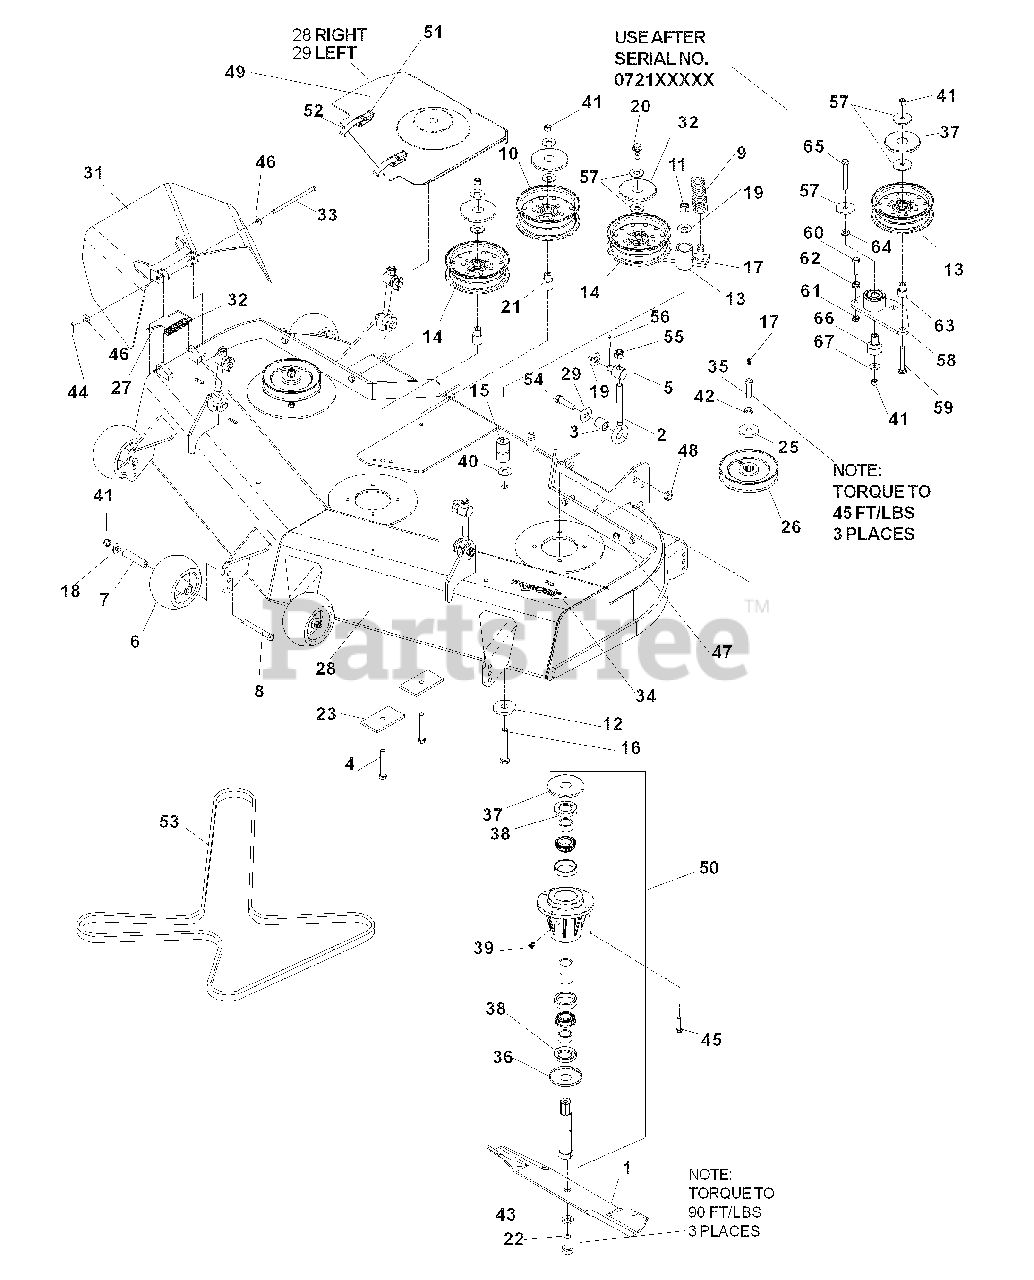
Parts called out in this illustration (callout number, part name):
1	BLADE, 18"
4	HCS, 3/8-16 x 2 3/4
6	ROLLER, ANTI SCALP
8	HCS, 3/8-16 x 3 1/2, GR8
9	SPRING, EXTENSION
10	PULLEY, IDLER
11	NUT, 1/2-13, NYLOC
12	WASHER, .65
14	PULLEY, IDLER
15	BUSHING, PIVOT
16	HCS, 1/2-13 x 3 1/4
17	ZERK, STRAIGHT, 1/4-28
18	WASHER, 3/8
19	WASHER, 9/16
20	HCS, 3/8-16 x 1
21	BUSHING, IDLER
22	HCS, 5/8-18 x 1 1/4
23	PAD
24	SPRING WASHER, 1/2
25	WASHER, .469
27	CAP-SLEEVE
28	DECK W/DECALS
29	BELT SHIELD, RIGHT
30	BELT SHIELD, LEFT
31	DISCHARGE CHUTE
32	SPRING, TORSION
33	PIN-CLEVIS, 5/16 DIA x 5.19
34	DECAL, TUNNEL RAM
35	HCS, 7/16 -20 x 1 1/2, GR8
36	BOTTOM DUST CAP
37	TOP DUST CAP
38	SHAFT SEAL
39	PLUG, VENTED
40	WASHER, 1/2
41	NUT, 3/8-16, NYLOC
42	LOCKWASHER, 7/16
43	LOCKWASHER, 5/8
44	PIN COTTER, 1/8 x 3/4
45	HCS, 5/16-18 x 1 1/4
46	WASHER, 5/16
47	NUT, 5/16-18, NYLOC
48	NUT, 7/16-14, CNTRLCK, GR A
49	DECAL, EURO SEVERING
50	SPINDLE ASSEMBLY
52	DRAW LATCH
53	DECK BELT
54	HCS, 7/16-14 x 1 3/4
55	NUT, 1/2-13, NYLOC
56	PIN, COTTER, 1/8 x 1
57	WASHER, 3/8, SPEC
58	ARM, IDLER, W/BEARINGS
59	RHSNB, 3/8-16 x 2 3/4
60	HCS, 3/8-16 x 1 1/2, GR8
61	NUT, 3/8-16, JAM
62	NUT, 3/8-16, WHIZLK
63	BUSHING, IDLER
64	WASHER, 3/8, SAE
65	HCS, 3/8-16 x 3
66	PIVOT, BEARING
67	WASHER, 3/8
